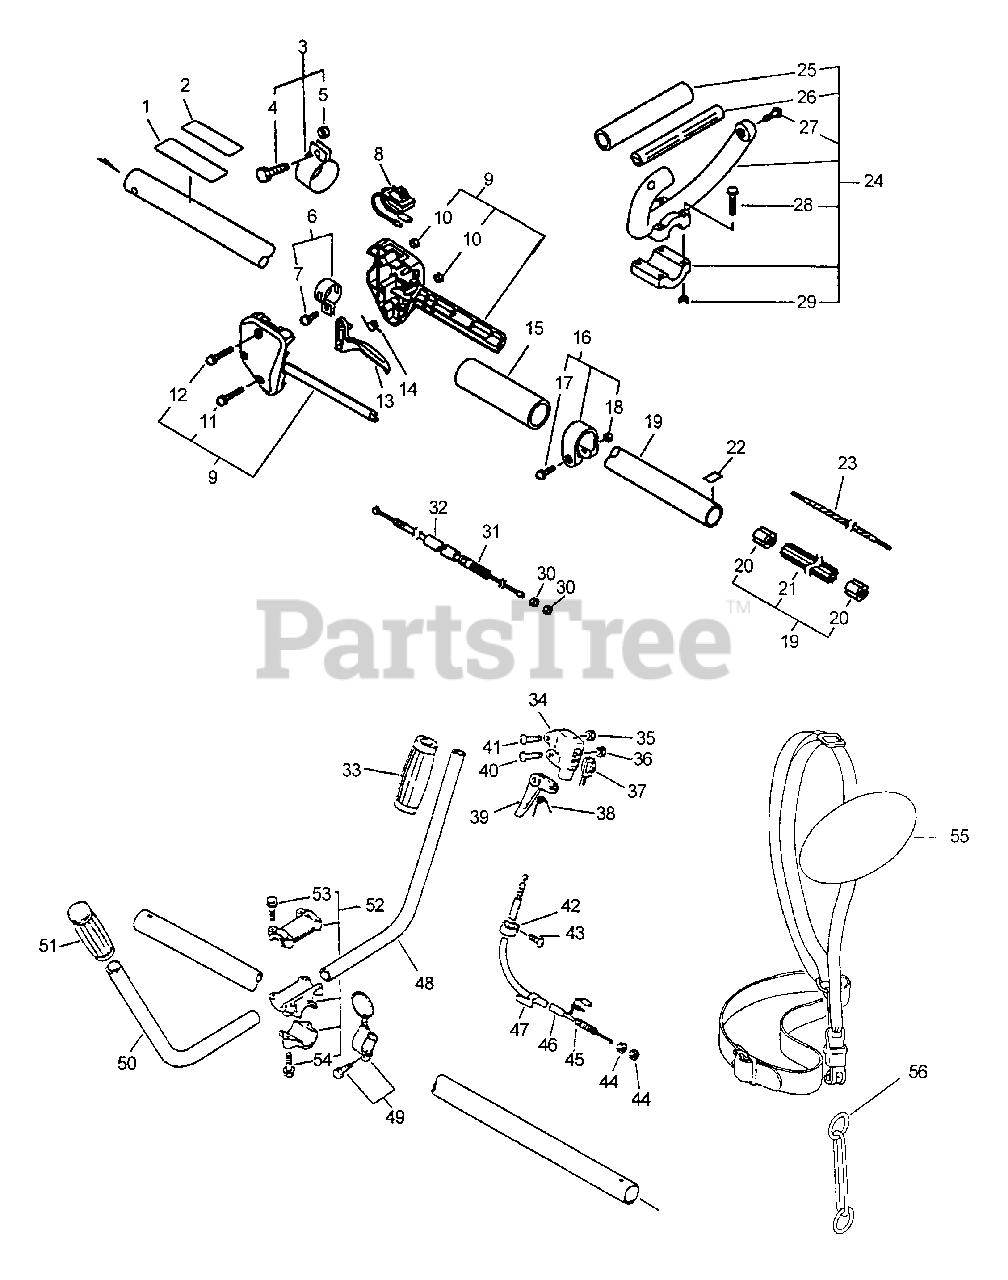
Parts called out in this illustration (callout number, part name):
1	LABEL, CAUTION
2	LABEL, CAUTION
3	HOOK
4	BOLT 5×18
5	SPACER, GUARD
6	CLAMP KIT
7	SCREW 5×14
8	SWITCH, ON-OFF
9	HANDLE KIT, CONTROL
10	NUT M5
11	SCREW 5×25
12	SCREW 5×35
13	TRIGGER, THROTTLE
14	SPRING, TORSION
15	GRIP, HANDLE
16	CLAMP KIT
17	SCREW 5×28
18	NUT M5
19	MAIN PIPE ASSY
21	LINER, FLEXIBLE 21.6×1420
22	LABEL - ALIGNMENT
23	DRIVESHAFT - FLEXIBLE L= 1522
24	LOOP HANDLE ASSY
25	GRIP, HANDLE
27	SCREW 5×30
28	SCREW 5×35
29	NUT M5
31	CABLE, THROTTLE
32	TUBE - VINYL
34	BRACKET, THROTTLE
35	NUT M5
36	NUT, LOCK M5
37	SWITCH, ON-OFF
39	TRIGGER, THROTTLE
41	SCREW 5×25
43	SCREW 5×10
45	CABLE, THROTTLE
49	HOOK
50	HANDLE, LEFT
51	GRIP, HANDLE
52	HANDLE BRACKET KIT
53	BOLT 5×25
54	BOLT - 6×30
55	SHOULDER STRAP ASSY
56	RING, HARNESS Ø32
